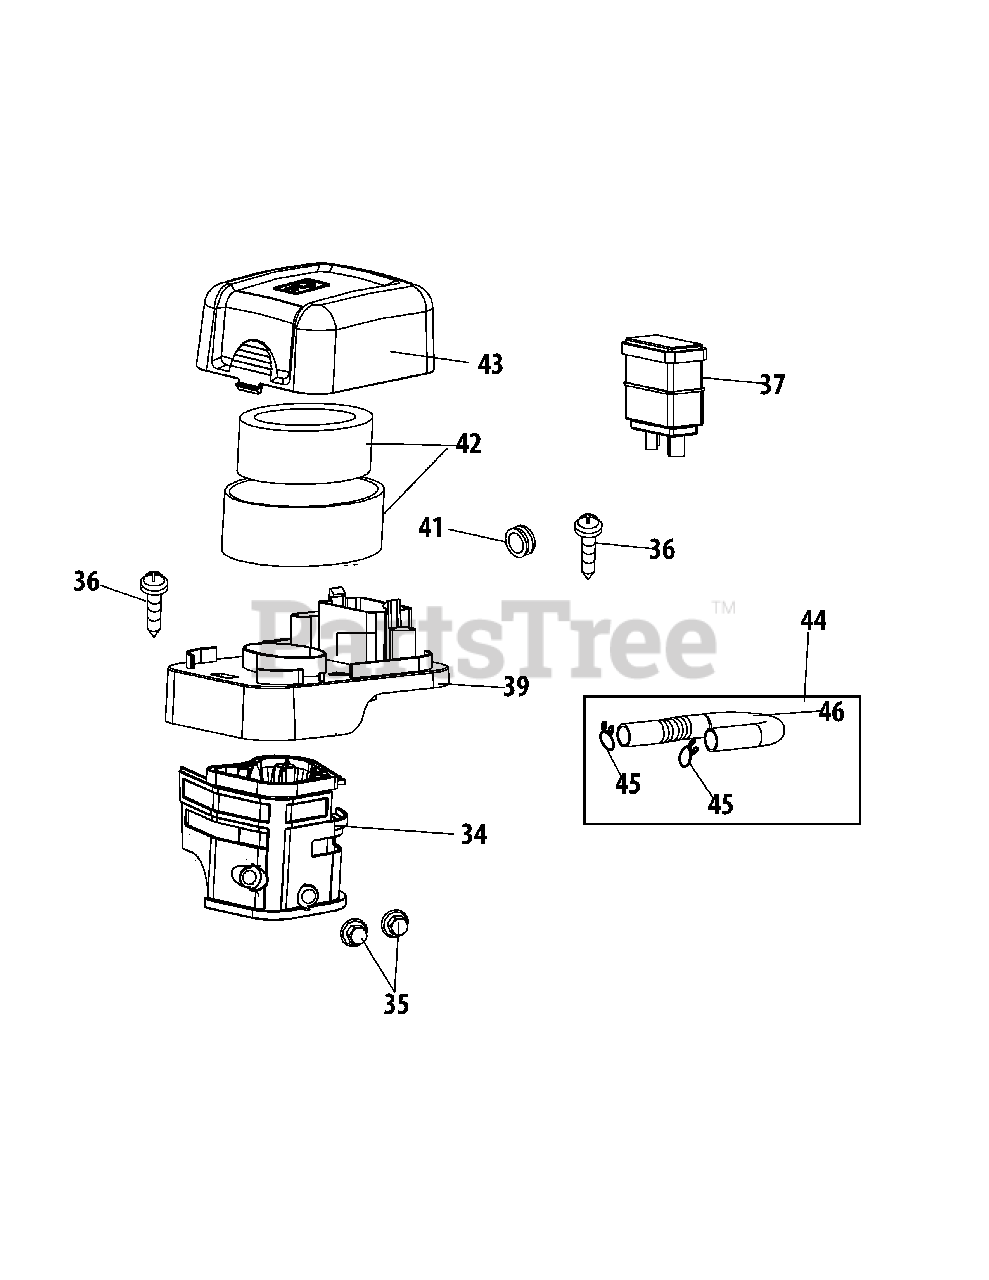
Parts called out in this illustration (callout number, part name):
34	Air Cleaner Housing
36	Self-Tapping Bolt4.2×20
37	Carbon Canister
39	Silencer Plate
41	Damper Gasket
42	Air Filter Assembly
43	Air Cleaner Cover
45	Piping Hose Clamp
46	Exhaust Piping
